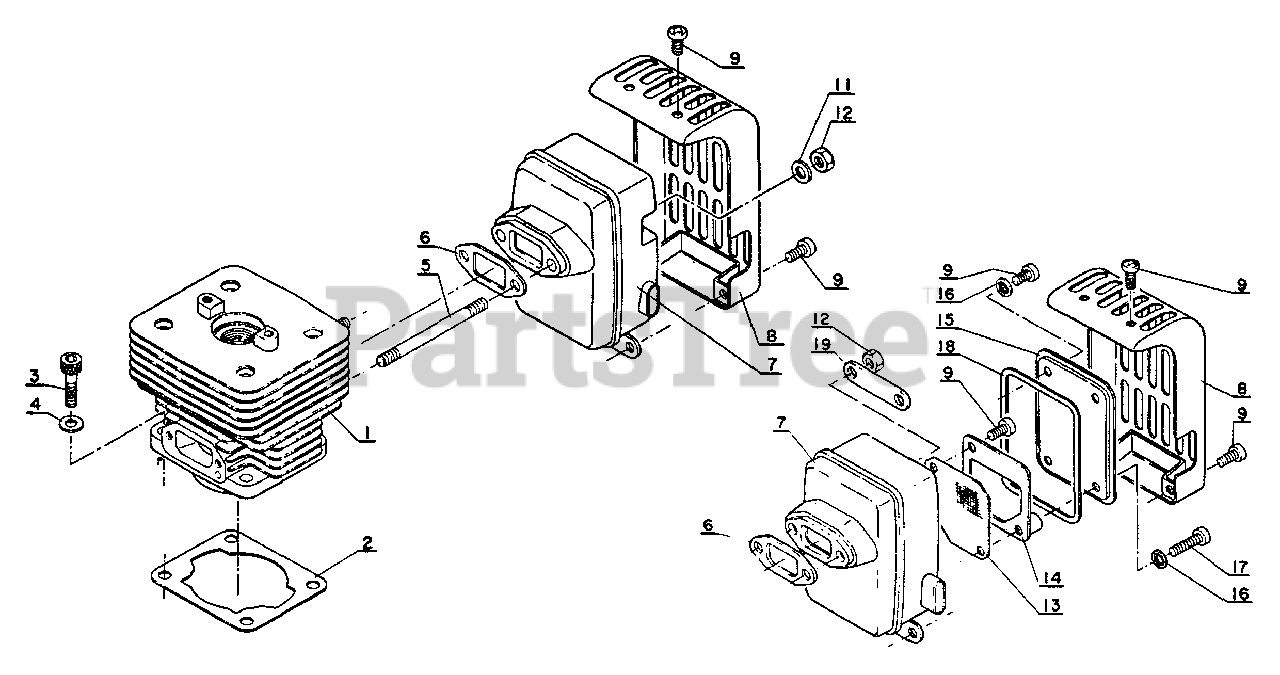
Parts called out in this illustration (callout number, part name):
1	CYLINDER
2	GASKET, CYLINDER
3	SCREW - 5X20
4	WASHER - 5
5	STUD
6	GASKET, EXHAUST
7	MUFFLER
8	COVER, MUFFLER
9	SCREW - 4X8
11	WASHER - 5
12	LOCKNUT - 5
13	SCREEN, SPARK ARRESTOR
14	RETAINER, SCREEN
15	COVER, MUFFLER
16	LOCKWASHER - 4
17	SCREW - 4X18
18	GASKET, EXHAUST
